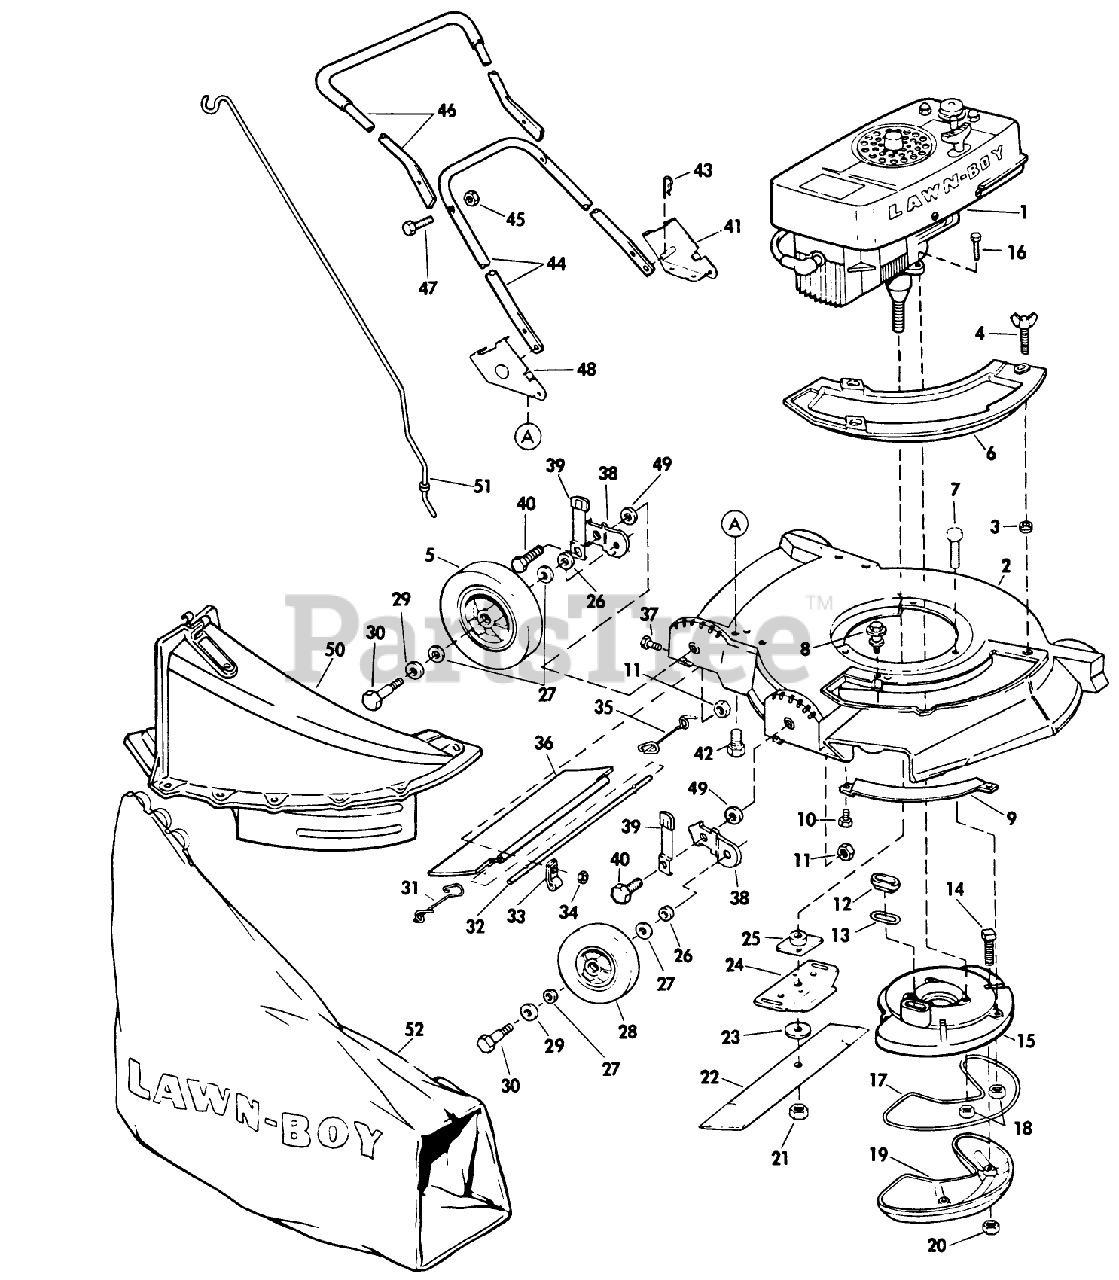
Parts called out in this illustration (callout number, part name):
1	See Note #2 at bottom of this page.
4	WING SCREW LAWRE
9	TOE BAR 19"
9	BAR-TOE
11	LOCKNUT
13	GASKET S
18	NUT-LOCK F
21	NUT-BLADE
23	WASHER
25	PLATE AND COLLAR ASM
26	WASHER WROUGHT
28	WHEEL & TIRE KIT
30	BOLT WHEEL
31	SPRING;TRAILING SHIELD RH
32	ROD T/SHIELD ADV WIRE
33	CLAMP ROD KMC
34	LOCKNUT E
35	SPRIG T/SHLD ASOC
43	HAIR PIN
45	LOCKNUT E
51	ROD GRASSBAG
52	89802 LB WHOLE GOODS
